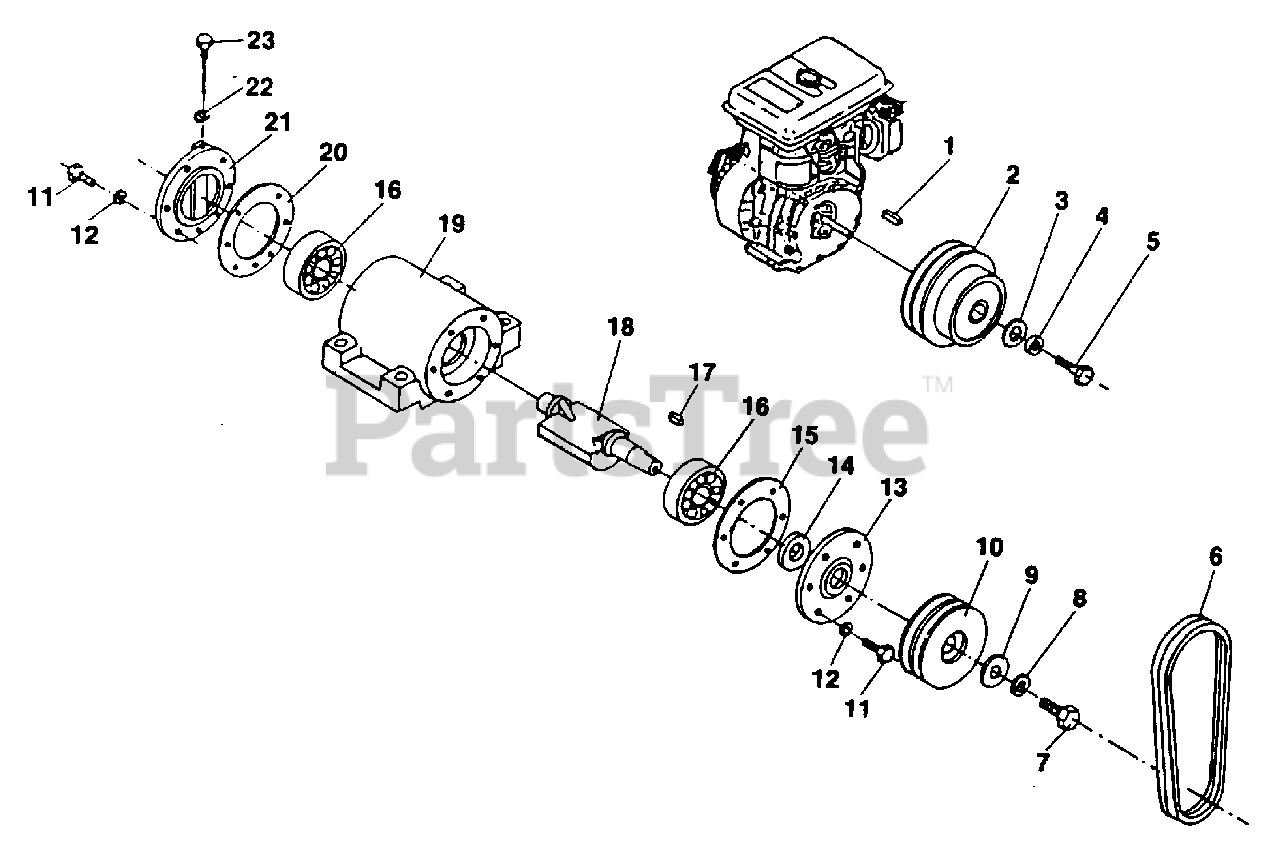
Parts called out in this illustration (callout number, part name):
1	KEY- Parallel
2	CLUTCH- Centrifugal
3	WASHER- Plate 5/16"
4	WASHER- Spring 5/16"
5	BOLT- Hex 5/16 x 11/2"
7	BOLT- Hex (m14 x 30")
8	WASHER- Spring (m14)
9	WASHER- Plate
10	PULLEY- V
11	BOLT- Hex (m8 x 20)
12	WASHER- Spring (m8)
13	HOLDER- Bearing
14	SEAL- Oil
17	KEY- Parallel (10 x 8 x 25)
18	VIBRATOR UNIT
19	CASE- Vibrator Unit
21	HOLDER- Bearing
22	WASHER- Spring (m16)
23	GAUGE- Oil level
